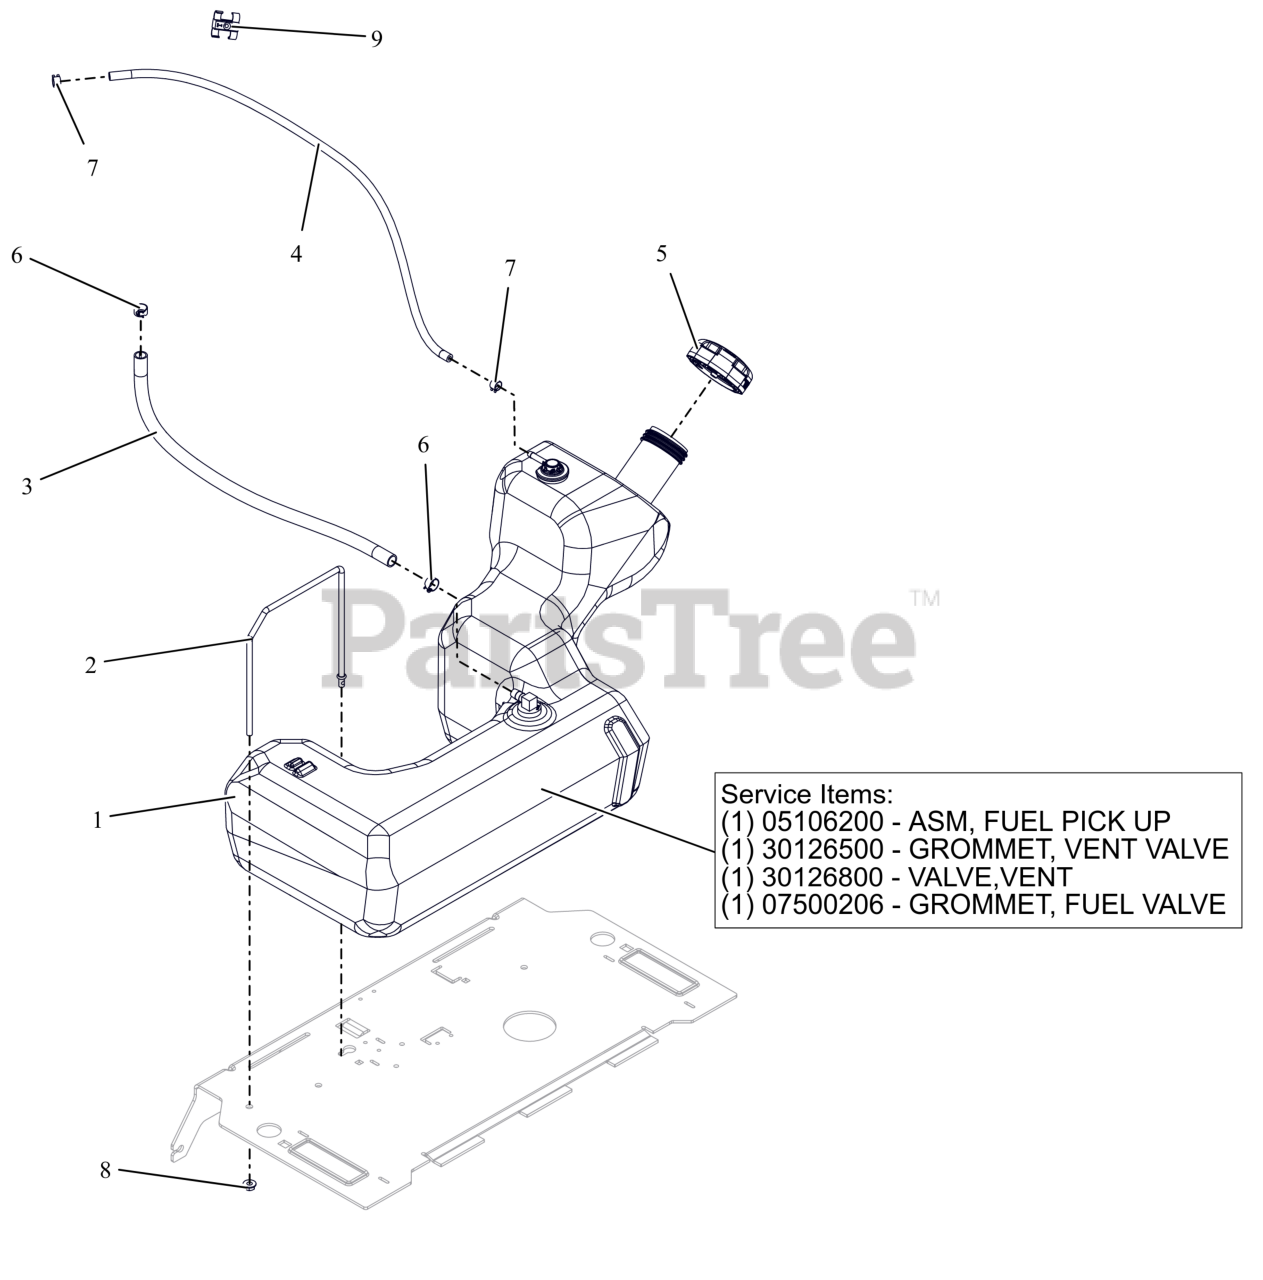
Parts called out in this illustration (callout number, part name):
1	ASM, FUEL TANK - IKON 23
1	ASM, IKON FUEL PICK-UP
1	GROMMET, VENT VALVE
1	VALVE, VENT
1	BSHG-FLG .375X1.062X.625 NITR
2	STRAP- TANK HOLD DOWN
3	HOSE, .25 LOW-PERM BULK GAS
4	HOSE, .188 30R7 BULK
5	CAP, FUEL - 2.25 RATCHET INLET VENT
6	CLAMP, FUEL LINE
7	CLAMP-HOSE, SPRING .188
8	NUT-LK-CTR-FLG .25-20 ZC120
9	CLIP, T, .38-.50
